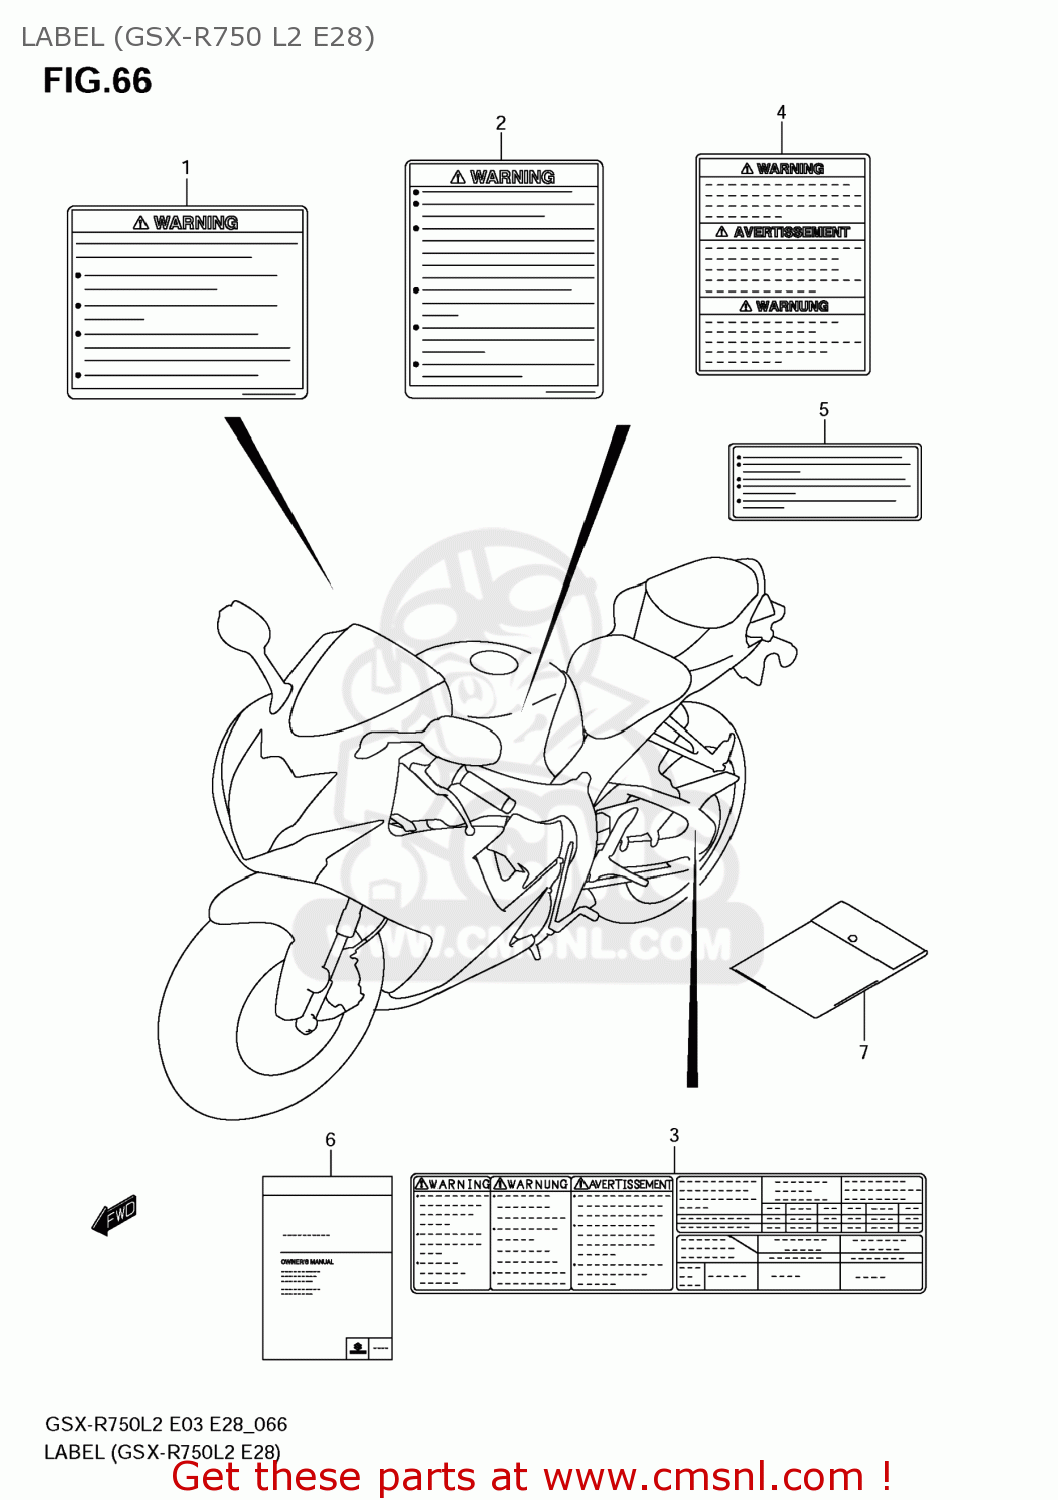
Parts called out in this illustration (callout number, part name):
1	LABEL,GENERAL WARNING
2	LABEL,SCREEN
3	LABEL,TIRE INFORMATION
4	LABEL,WARNING STEERING
5	LABEL,FUEL INFORMATION
6	MANUAL,OWNER'S
7	BAG,OWNER'S MANUAL
